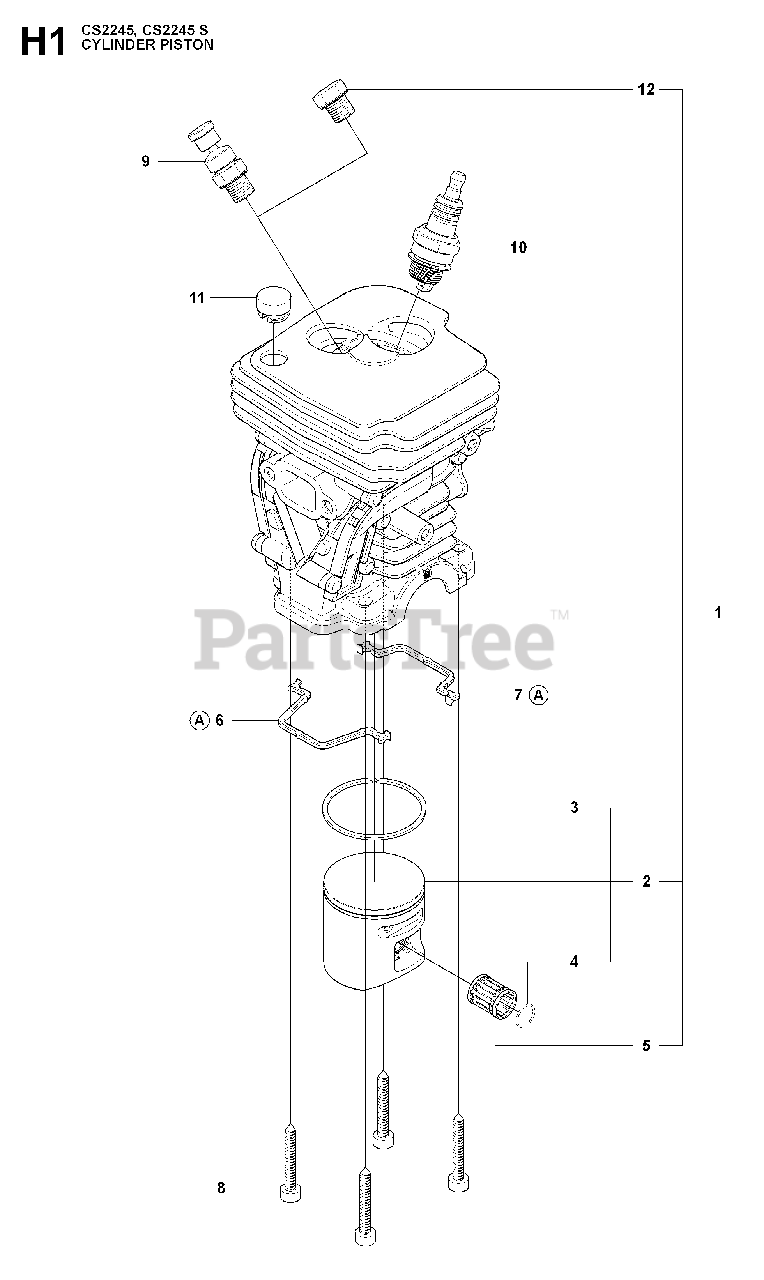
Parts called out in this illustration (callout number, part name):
2	PISTON ASSY
3	PISTON RING
5	RP SUPPORT BUSHING
9	DECOMPRESSION VALVE
10	BPMR7A NGK SPARK PLUG
12	CYLINDER PLUG
